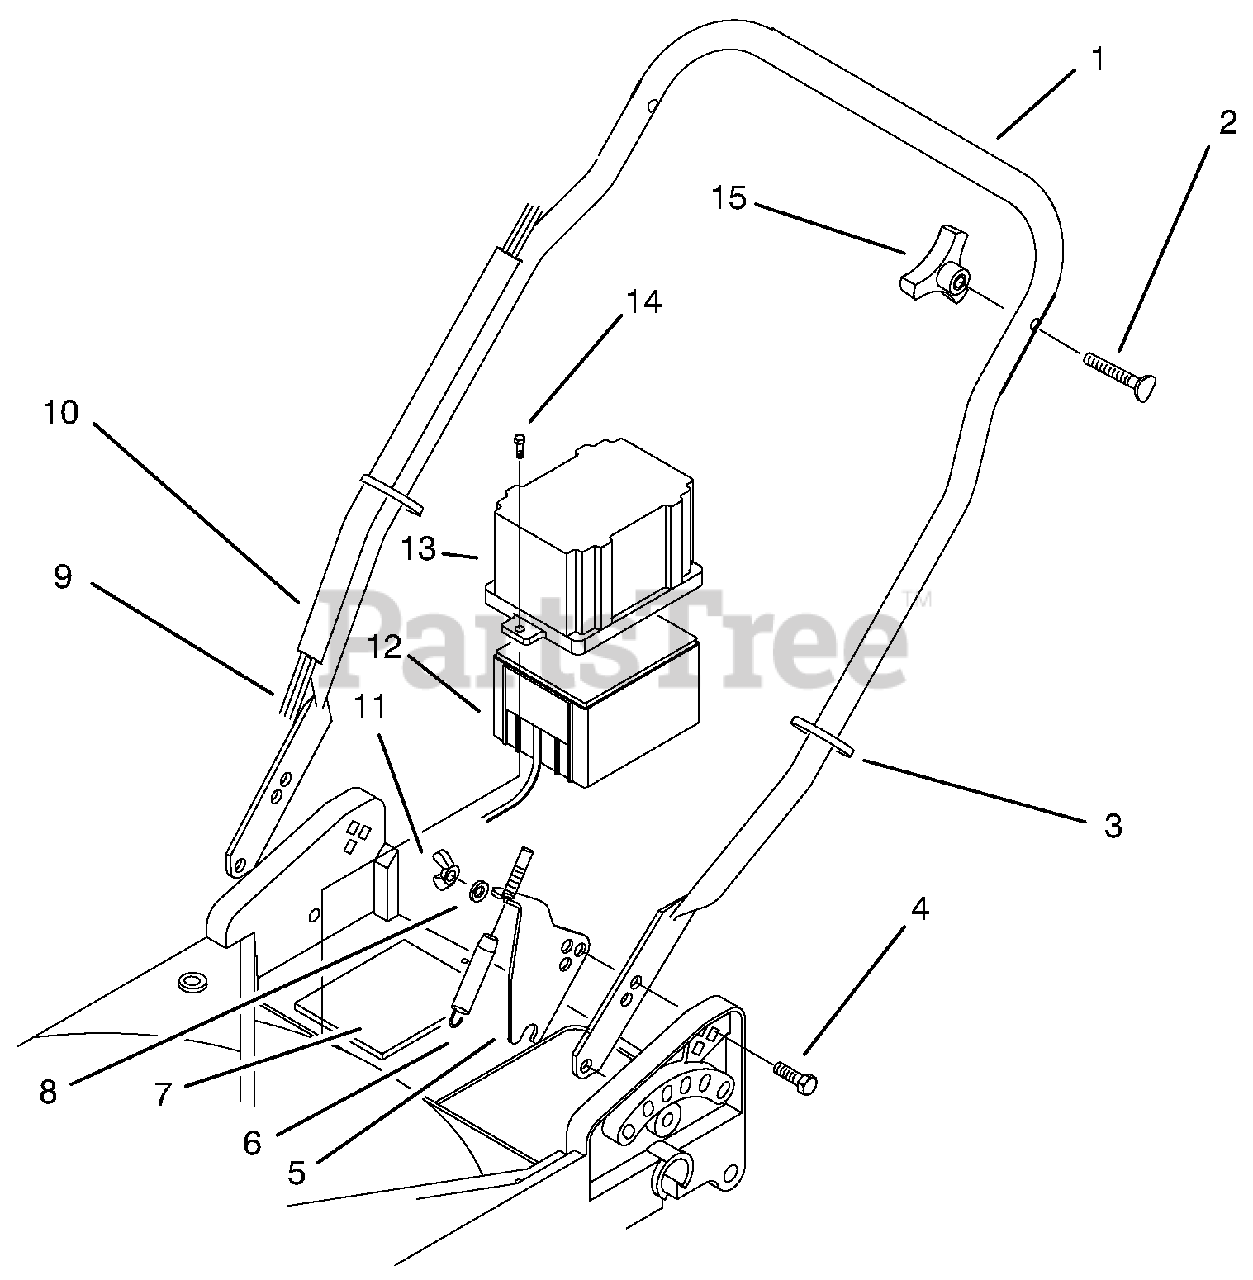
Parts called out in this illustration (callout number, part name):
1	Handle-Lower
2	Screw-Handle
3	Tie-Strap
4	Bolt-Carriage
5	Bracket-Traction Cable
6	Cable-Traction
7	Pad-Battery
8	Washer-Lock
9	Wire Assembly
10	Cover-Controls
12	Pack-Battery
13	Case-Battery
14	Screw-Hex Washer Hd. Thread Forming
15	Knob
